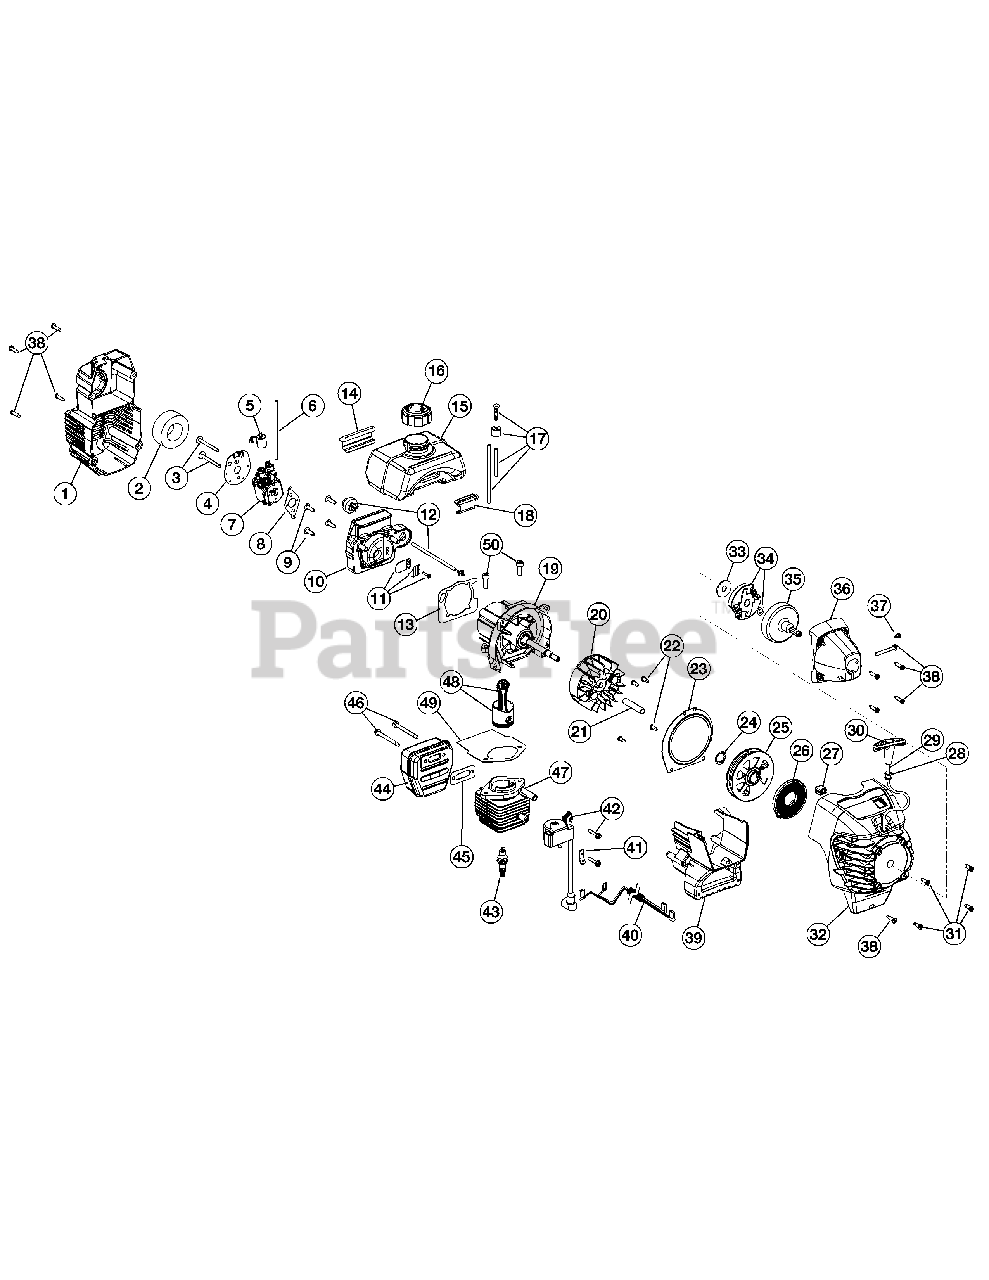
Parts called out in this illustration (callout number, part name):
1	Air Cleaner Cover Assembly (includes 2 & 38)
2	Air Cleaner Filter
3	Carburetor Mounting Screw Assembly
4	Choke Plate
5	Choke Lever
6	Fuel Return Line
7	Carburetor Assembly (includes 8 & 17)
8	Carburetor Gasket
9	Carb Mount Screw
10	Carb Mount Assembly (includes 9, 11 & 13)
11	Reed Assembly
12	Primer and Hose Assembly
13	Carburetor Mount Gasket
14	Rear Mounting Pad
15	Fuel Tank Assembly (includes 6, 16 & 17)
16	Fuel Cap Assembly
17	Fuel Line Assembly
18	Front Mounting Pad
19	Crank Case Service Assembly (includes 9)
20	Flywheel Assembly
22	Pressure Plate Screw
23	Pressure Plate Screw (includes 22)
24	Pulley Retainer
25	Recoil Pulley Assembly (includes 24)
26	Recoil Spring
27	Rope Guide Retainer
28	Rope Guide
30	Pull Handle
31	Housing Screw
32	Starter Housing Assembly (includes 22-31 & 38)
33	Clutch Washer
34	Clutch Rotor Assembly
35	Clutch Drum Assembly
36	Clutch Cover Assembly (includes 37 & 38)
37	Anti-Rotation Screw
38	Cover Screw
39	Shroud Extension & Stand (includes 38)
40	Wire Leads and Sleeve
41	Ground Tab
42	Module Assembly
43	Spark Plug
44	Muffler Assembly (includes 45 & 46)
45	Exhaust Gasket
46	Muffler Mounting Bolt Assembly
47	Cylinder Assembly (includes 48 & 49)
48	Piston and Rod Assembly
49	Cylinder Gasket
50	Cylinder Bolt
